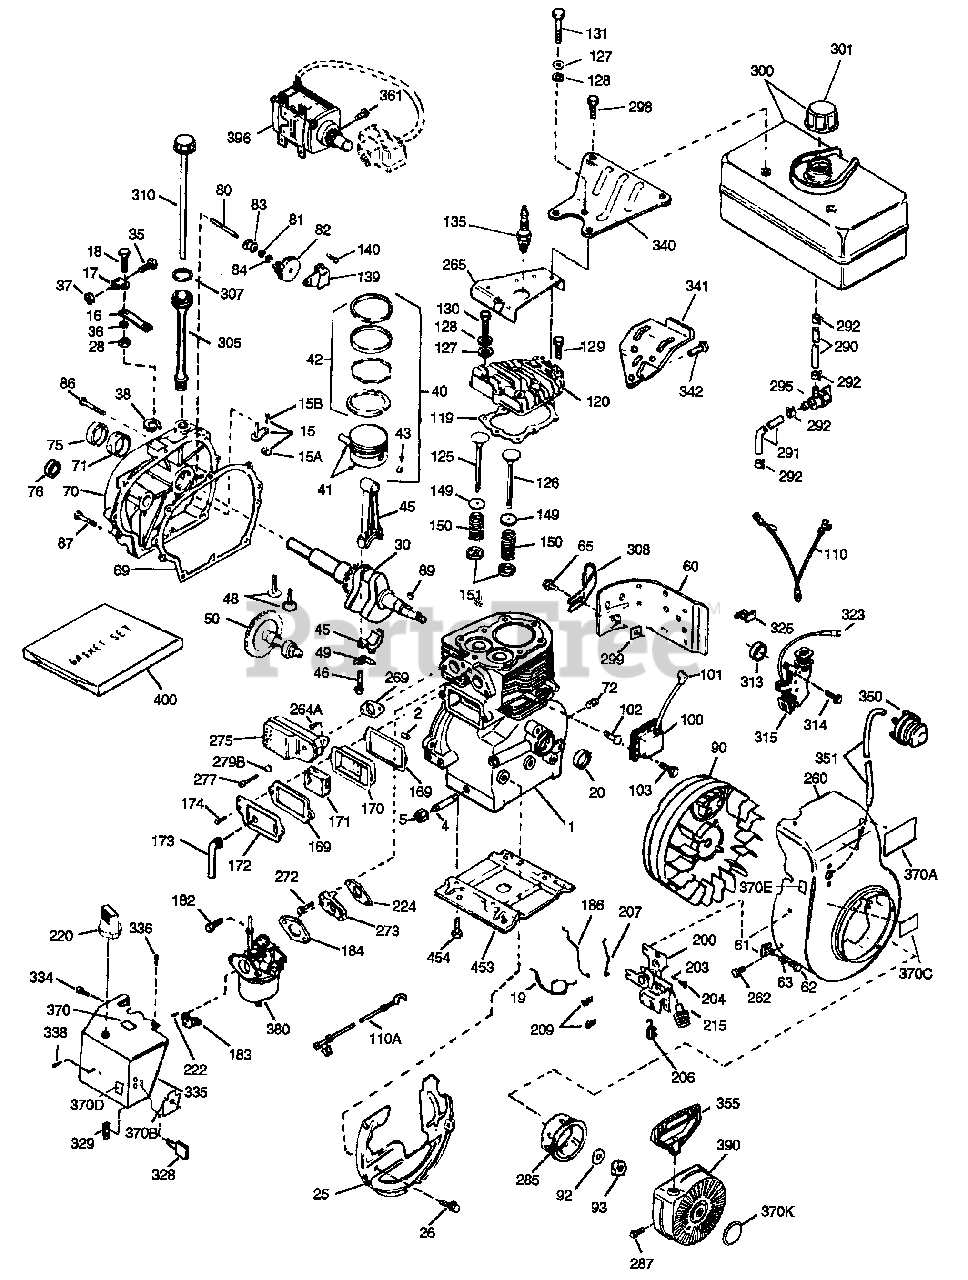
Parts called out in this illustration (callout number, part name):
2	Dowel Pin
4	Oil Drain Extension
5	Extension Cap
15	Governor Rod
15A	Governor Yoke
15B	Screw, 6-40 x 5/16"
16	Governor Lever
17	Governor Lever Clamp
18	Screw, 8-32 x 5/16"
19	Speed Control Spring
25	Blower Housing Baffle
26	Screw, 1/4-20 x 5/8"
28	Lock Nut, 8-32
30	Crankshaft
35	Screw , 10-32 x 3/4"
36	Lock Washer
37	Lock Nut, 10-32
38	Retaining Ring
40	Piston, Pin, Ring Set (Std)
41	Piston & Pin Assy (Std)
42	Ring Set (Std)
43	Piston Pin Retaining Ring
45	Connecting Rod Assy
46	Connecting Rod Bolt
48	Valve Lifter
49	Oil Dipper
60	Blower Housing Extension
61	Grommet Mounting Bracket
62	Screw, 8-32 x 3/8"
65	Screw, 10-24 x 1/2"
69	Cylinder Cover Gasket
70	Cylinder Cover
71	Crankshaft Bushing
72	Oil Drain Plug
76	Camshaft Seal
80	Governor Shaft
82	Governor Gear Assy
83	Governor Spool
84	Retaining Ring
86	Screw, 1/4-20 x 1-1/4"
87	Screw, 1/4-20 x 1-3/4"
89	Flywheel Key
92	Belleville Washer
93	Flywheel Nut
100	Solid State Ignition
101	Spark Plug Cover
102	Solid State Mounting Stud
103	Screw, Torx T-15, 10-24 x 15/16"
110	Ground Wire
110A	Ground Wire
119	Cylinder Head Gasket
120	Cylinder Head
125	Exhaust Valve (Std)
126	Intake Valve (Std)
128	Belleville Washer
129	Screw, 5/16-18 x 2-1/2"
130	Screw, 5/16-18 x 2-1/2"
131	Screw, 5/16-18 x 2-1/2"
135	Resistor Spark Plug
139	Governor Gear Bracket
140	Screw, Torx T-25, 10-24 x 1/2"
149	Valve Spring Cap
150	Valve Spring
151	Valve Spring Keeper
169	Breather Gasket
170	Breather Body
171	Breather Element
172	Valve Cover
173	Breather Tube
174	Screw, 10-24 x 1/2"
182	Screw, 1/4-20 x 27/32"
183	Choke Bracket
184	Carburetor to Intake Pipe Gasket
186	Governor Link
200	Control Bracket
203	Compression Spring
204	Screw, 5-40 x 7/16"
207	Throttle Link
209	Screw, 10-32 x 1/2"
215	Control Knob
220	Control Knob
222	Screw, 10-32 x 1/2"
224	Intake Pipe Gasket
260	Blower Housing
262	Screw, Torx T-40, 5/16-24 x 21/32"
264A	Screw, 5/16-18 x 3/4"
265	Cylinder Head Cover
269	Muffler Gasket
272	Screw, 5/16-18 x 3/4"
273	Carburetor Flange
277	Screw, 5/16-18 x 2"
285	Starter Cup
287	Screw, 8-32 x 21/64"
290	Fuel Line
291	Fuel Line
292	Fuel Line Clamp
295	Fuel Shut-Off Valve
298	Screw, 1/4-15 x 3/4"
299	"U" Type Nut
301	Fuel Cap
305	Oil Fill Tube
308	Fill Tube Clip
314	Screw, 1/4-20 x 3/4"
315	Alternator Coil
325	Wire Clip
328	Ignition Keys
334	Screw, 8-32 x 5/16"
335	Carburetor Cover
336	Screw, 10-32 x 1/2"
338	Screw, 8-32 x 3/8"
340	Fuel Tank Bracket
341	Fuel Tank Bracket
342	Screw, 1/4-20 x 5/8"
350	Primer Assy
351	Primer Line
355	Starter Handle
361	Screw, Torx T-30, 1/4-20 x 15/32"
370	Instruction Decal
370A	Control Decal
370B	Warning Decal
370C	Primer Decal
370D	Warning Decal
370E	Choke Decal
370K	Starter Decal
390	Rewind Starter
396	Electric Starter Motor
400	Gasket Set
453	Engine Mounting Base
454	Screw, 5/16-18 x 3/4"
